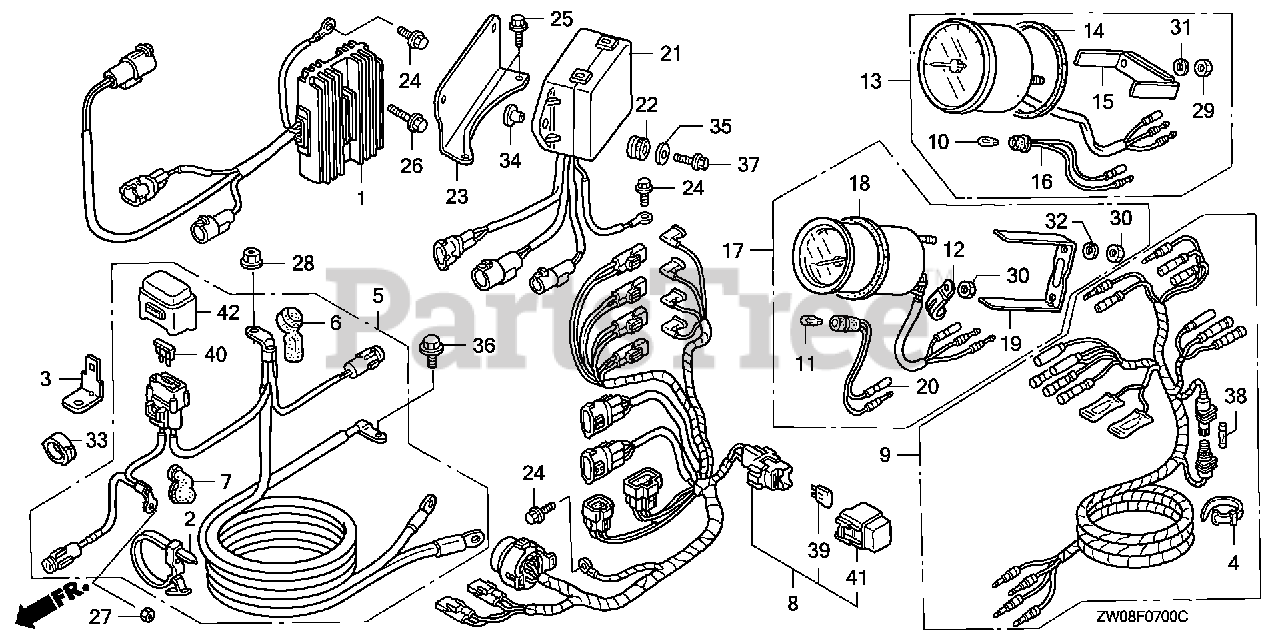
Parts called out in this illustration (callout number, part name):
1	RECTIFIER ASSY., REGULATOR (20A)
2	BAND, WIRE
3	BRACKET, FUSE
4	BAND B1, CABLE Use up to Frame SN 1001879.
5	CABLE ASSY., STARTER
6	COVER, STARTER TERMINAL
7	COVER, MAGNETIC SWITCH TERMINAL
8	CABLE ASSY., REMOTE CONTROL (A)
9	HARNESS ASSY., METER (A)
10	BULB, WEDGE BASE (T10) (12V 1.7W) (STANLEY)
13	TACHOMETER ASSY.
14	GASKET
15	BRACKET (TO 1015209) (FROM 1015210)
16	SOCKET (TO 1015209) (FROM 1015210)
21	RELAY ASSY., POWER TILT
22	GROMMET, RELAY
23	BRACKET, RELAY
24	BOLT, FLANGE (6X12) (CT200)
25	BOLT, FLANGE (6X14) (CT200)
26	BOLT, FLANGE (6X22) (CT200)
27	NUT, HEX. (6MM)
28	NUT-WASHER (8MM)
29	NUT, HEX. (5MM)
31	WASHER, SPRING (5MM)
33	CLIP, WIRE HARNESS
34	COLLAR, MODULE IGNITION CONTROL CASE (CDI)
35	WASHER, PLAIN (6MM)
36	BOLT, FLANGE (6X14)
37	BOLT, FLANGE (6X25)
38	FUSE A (10A)
39	FUSE, BLADE (15A)
40	FUSE, BLADE (30A)
41	COVER ASSY., FUSE (15A)
42	COVER ASSY., FUSE (30A)
